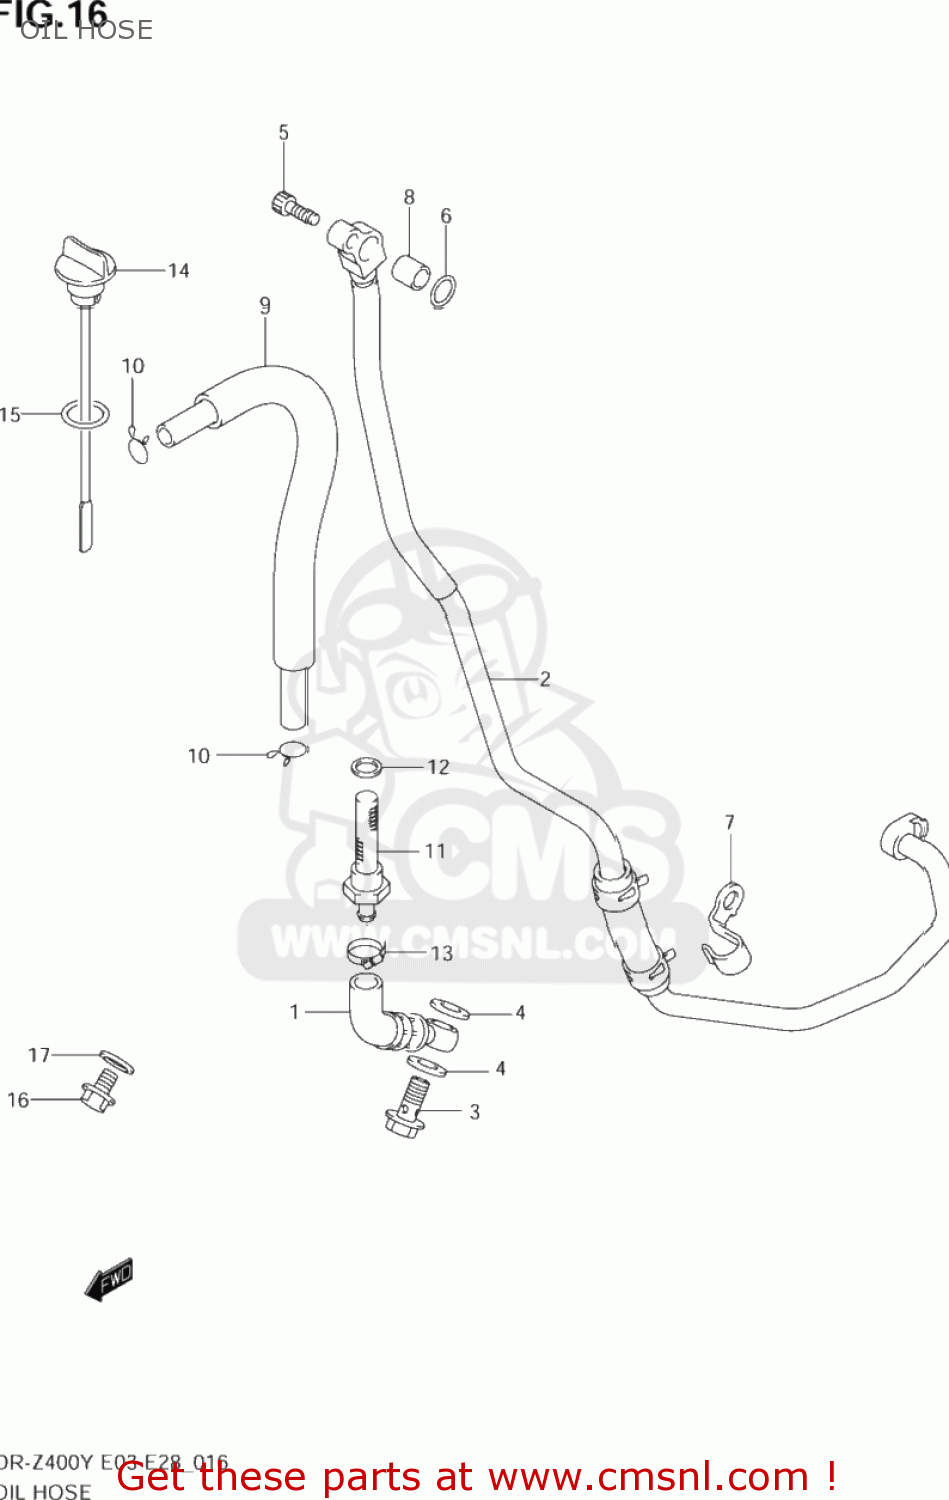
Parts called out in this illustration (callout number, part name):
1	HOSE,OIL TANK,R
2	HOSE,OIL TANK,L
3	BOLT UNION
4	GASKET(14X20X1.5) (NAS)
5	BOLT
6	O RING(D:2.4,ID:11)
7	CLAMP,OIL TANK HOSE
8	PIN
9	HOSE,OIL TANK OVER FLOW
10	CLIP
11	STRAINER,FRAME HEAD UNDER
12	GASKET(18X22X2) (NAS)
13	CLAMP
14	GAUGE,OIL LEVEL
15	O RING(D:3.1,ID:16.8)
16	PLUG(10X12)
17	GASKET(10X14X3.6) (NAS)
